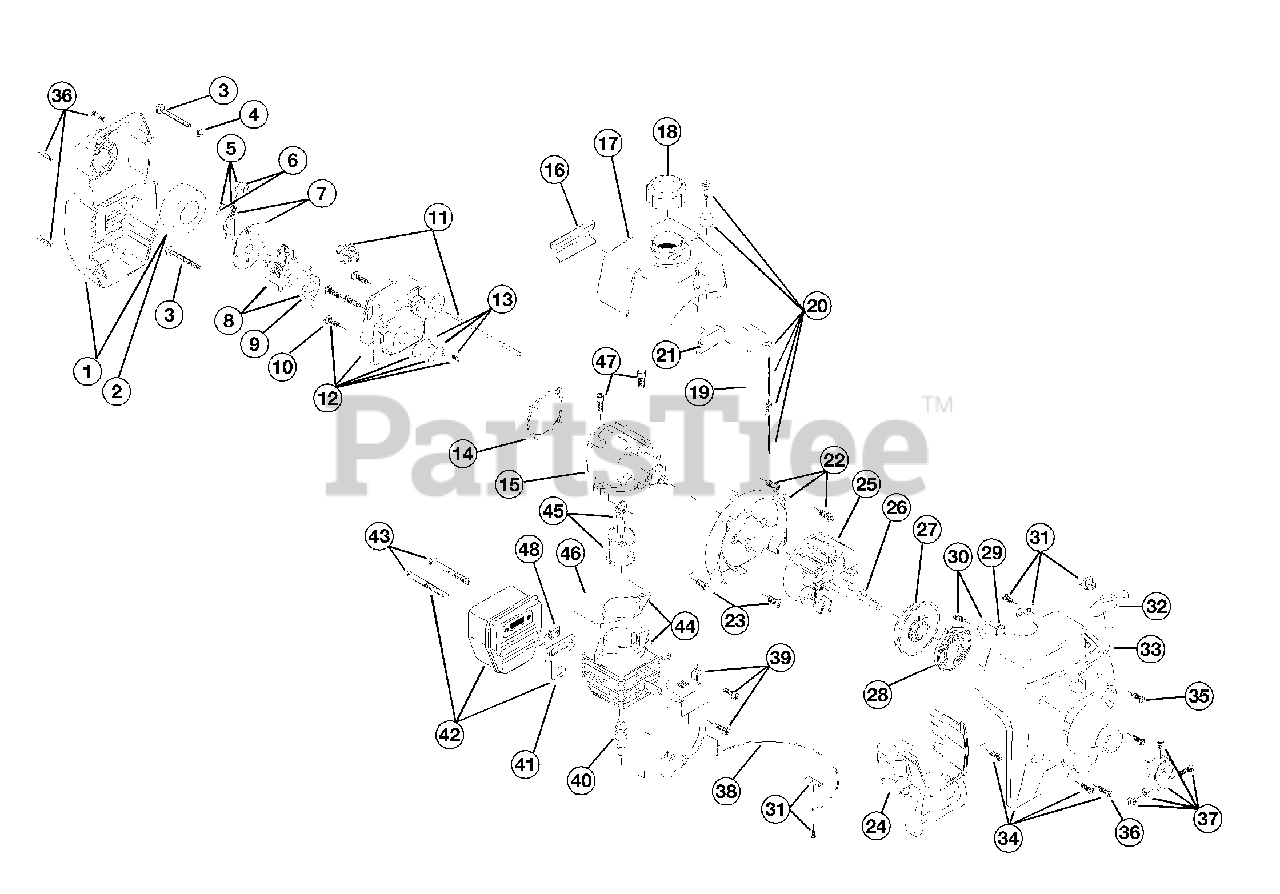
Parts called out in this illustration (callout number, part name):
1	Air Cleaner/Muffler Cover Assembly
2	Air Cleaner Filter
3	Carburetor Mounting Screw Assembly
4	Wavey Washer
5	Choke Lever Assembly
6	Choke Knob and Screw
7	Choke Lever and Plate
8	Carburetor Assembly
9	Carburetor Gasket
10	Carb Mount Screw
11	Primer and Hose Assembly
12	Carb Mount Assembly
13	Reed Assembly
14	Carburetor Mount Gasket
15	Crank Case Service Assembly
16	Rear Mounting Pad
17	Fuel Tank Assembly
18	Fuel Cap Assembly
19	Fuel Return Line
20	Fuel Line Assembly
21	Front Mounting Pad
22	Shroud Assembly
23	Shroud Screw
24	Shroud Extension and Stand
25	Flywheel Assembly
26	Square Nut Drive
27	Recoil Pulley Assembly
28	Recoil Spring
29	Rope Guide
30	Pulley Retainer Assembly
31	Switch Assembly
32	Pull Handle
34	Starter Housing Assembly
35	Housing Screw
36	Cover Screw
37	Upper Clamp Assembly
38	Wire Lead
39	Module Assembly
40	Spark Plug
41	Exhaust Gasket
42	Muffler Assembly
43	Muffler Mounting Bolt Assembly
44	Cylinder Assembly
45	Piston and Rod Assembly
46	Cylinder Gasket
47	Cylinder Bolt
48	Spark Arrestor Screen
